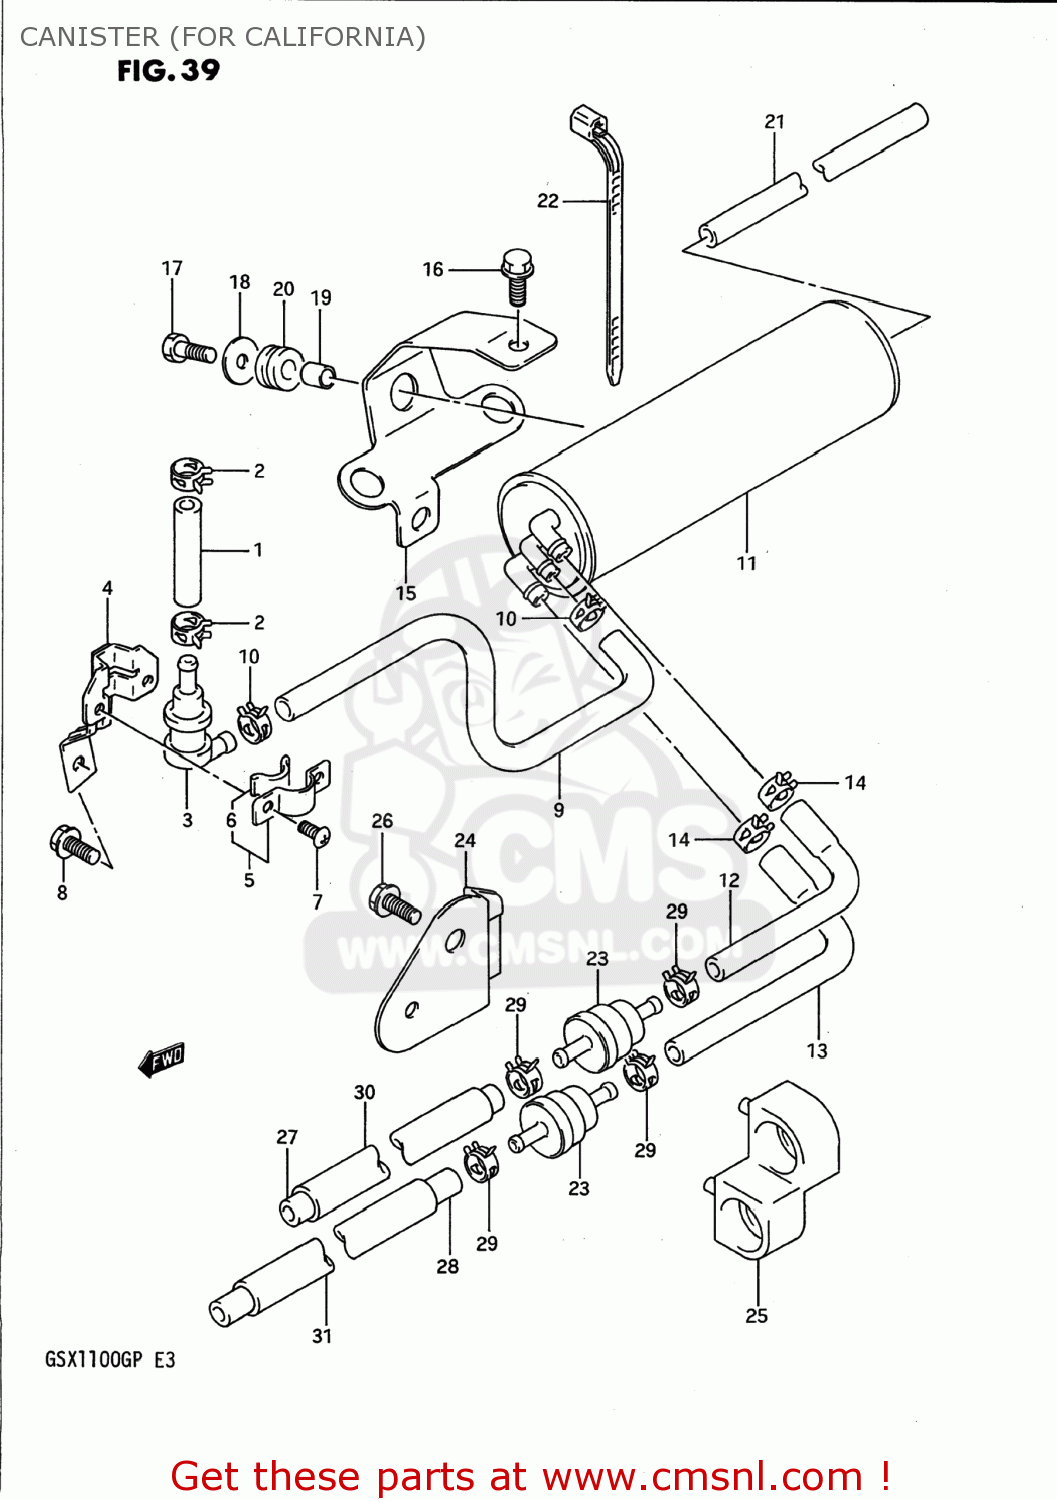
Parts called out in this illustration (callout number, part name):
1	HOSE
2	CLIP
3	VALVE,FUEL TANK BREATHER
4	BRACKET COMP,BREATHER VALVE
5	PLATE,FUEL TANK BREATHER NO.2
6	CUSHION
7	SCREW
8	BOLT
9	HOSE
10	CLIP
11	CANISTER ASSEMBLY,CHARCOAL
12	HOSE,PCV & CANISTER NO.1
13	HOSE,PCV & CANISTER NO.2
14	CLAMP
15	BRACKET,CANISTER
16	BOLT
17	BOLT
18	WASHER
19	SPACER
20	CUSHION
21	HOSE
22	CLAMP(L:125)
23	VALVE,CANISTER PURGE
24	BRACKET,CANISTER PURGE VALVE
25	(CA) CUSHION,CANISTER P VA
26	BOLT
27	HOSE (5.4X11.4X600)
28	HOSE (5.4X11.4X600)
29	CLIP
30	PROTECTOR,FUEL HOSE
31	PROTECTOR
